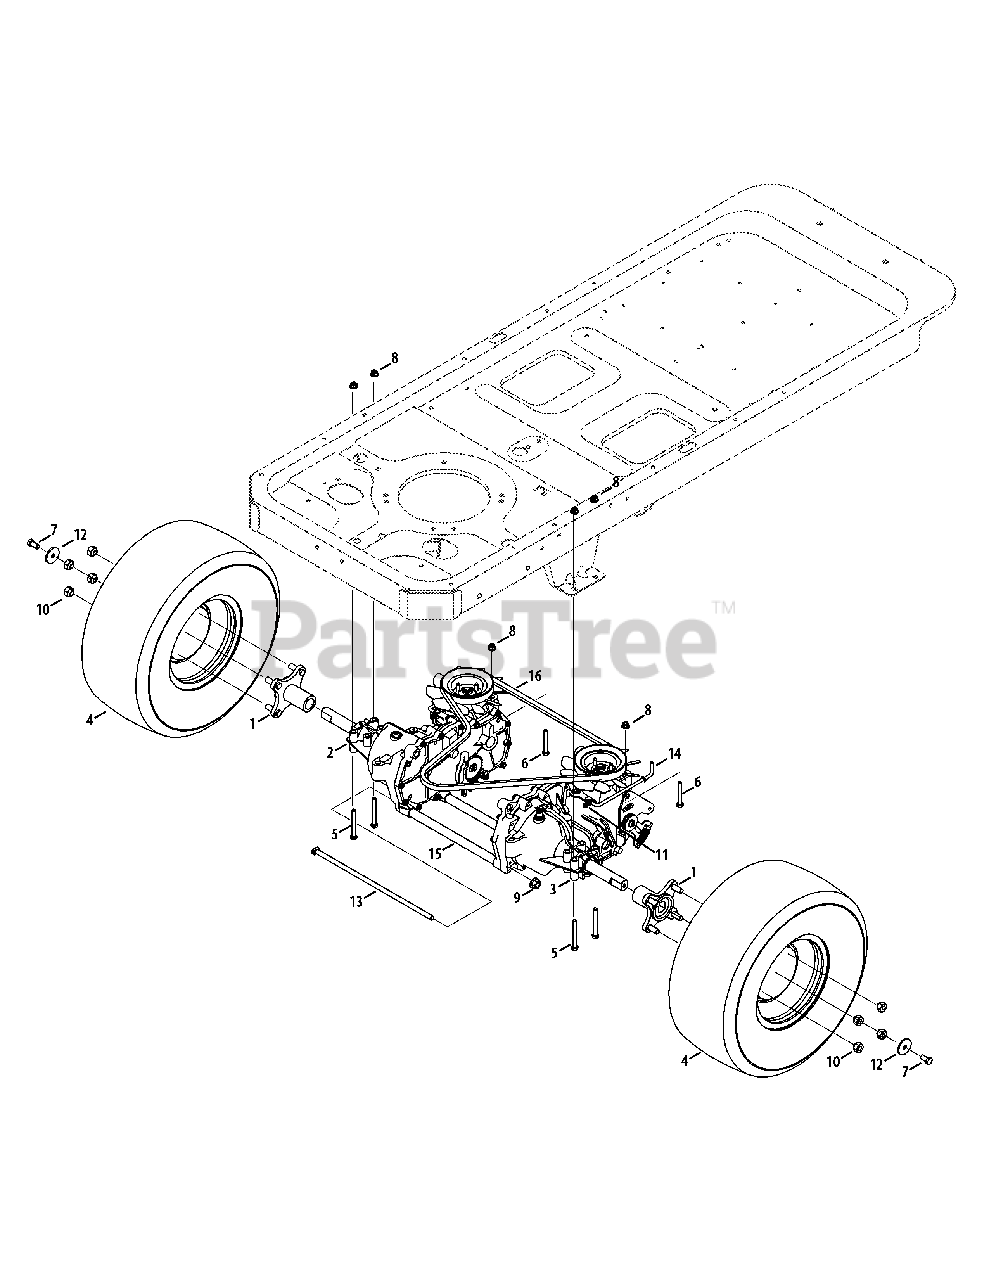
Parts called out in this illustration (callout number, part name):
1	Wheel Hub, 7/16-14 x 1.6
2	Transmission Assembly, LH
3	Transmission Assembly, RH
4	Wheel Assembly, 18 x 8.5-8
4	Wheel Assembly, 18 x 9.5-8
5	Hex Cap Screw, 5/16-18 x 2.75
6	Hex Cap Screw, 5/16-18 x 2.25
7	Hex Cap Screw, 3/8-16 x .75
8	Hex Flange Nut, 5/16-18
9	Hex Flange Nut, 7/16-20
10	Lug Nut, 7/16-14
11	Bow-Tie Cotter Pin
12	Flat Washer, .39 x 1.5
13	Rod, .405 x 14
15	Tube, .45 x .69 x 10.2
